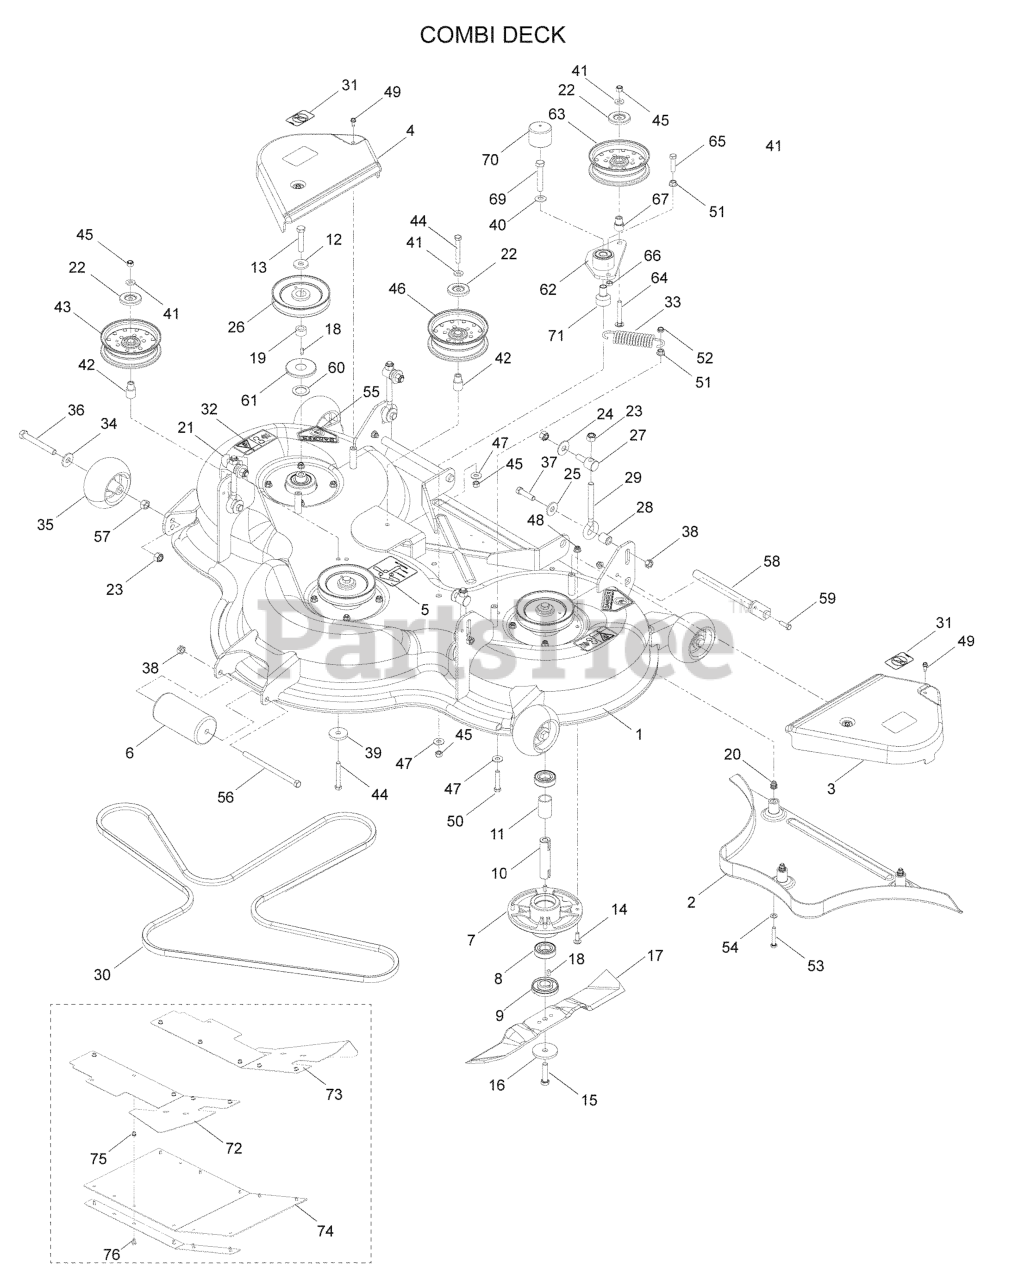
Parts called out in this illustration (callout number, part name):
1	DECK W/DECALS 52I HUS
3	BELT SHIELD LT
4	BELT SHIELD RT
5	DECAL, BELT ROUTING
6	ROLLER
7	BEARING HOUSING
8	BALL BEARING
9	BUSHING, BLADE
12	WASHER-.533IDX1.37OD
13	HCS M12 X 1.75 X 60 GR5 ZD
14	RHSNB 5/16C X 1
15	HCS M12 X 1.75 X 50 GR8.8 ZD
17	BLADE
19	KEY RETAINER
20	BLIND RIVET NUT
22	DUST SHIELD
23	NUT 1/2-13 HEX NYLOC ZD
24	WASHER 1/2 FLAT
25	SPRING WASHER - .50
26	PULLEY, 52
27	SWIVEL, DECK HEIGHT ADJ
30	BELT, DECK - ESTATE
31	DECAL, NO STEP
32	DECAL, BELT DRIVE
34	WASH USS FLAT 1/2
35	GAUGE WHEEL
36	HCS 1/2-13 X 4 GR 5 ZD
37	HCS 7/16 - 14 X 1 3/4
38	NUT 7/16C CENTERLOCK
39	SPINDLE WASHER
40	CONTACT BELLSPR 1/2
41	WASHER, 3/8 THICK
42	IDLER BUSHING
43	IDLER PULLEY
44	SCREW 3/8C X 2 3/4 HEX CAP
45	NUT 3/8-16 NYLOC
46	IDLER PULLEY (TALL)
47	WASHER 3/8 FLAT
48	5/16-18 NYLOC FLANGE NUT
49	SCREW 1/4 X 5/8
50	HCS 3/8C X 2
51	NUT 3/8C WHIZ
52	NUT HEX 3/8-16 NYLON, THIN
53	HCS M8 X 1.25 X 50 GR8.8 ZD
54	FLAT WASHER 5/16 SAE
55	DECAL, CPSC
56	HCS 7/16-14 X 7 GR5 ZD
57	NUT HEX 1/2
59	HCS 5/16C X 1
60	WASHER-1.06IDX1.63ODX.06
61	BOTTOM DUST CAP
62	ARM-IDLER W/BRG
63	IDLER PULLEY
64	CARRIAGE BOLT 3/8-16 X
65	HCS 3/8-16 X 1-1/2
66	NUT 3/8-16 HEX JAM
67	BUSHING, IDLER
68	WASHER 3/8 SAE FLAT
69	SCREW 3/8C X 2 3/4 HEX CAP
70	CAP, VINYL
71	PIVOT, BEARING
72	GUARD, DEBRIS, RT, BLK
73	GUARD, DEBRIS, LT, BLK
74	GUARD, RUBBER
75	STRAP, GUARD, BLK
76	KNURLED INSERT
77	SCREW- 1/4-20 X 5/8
